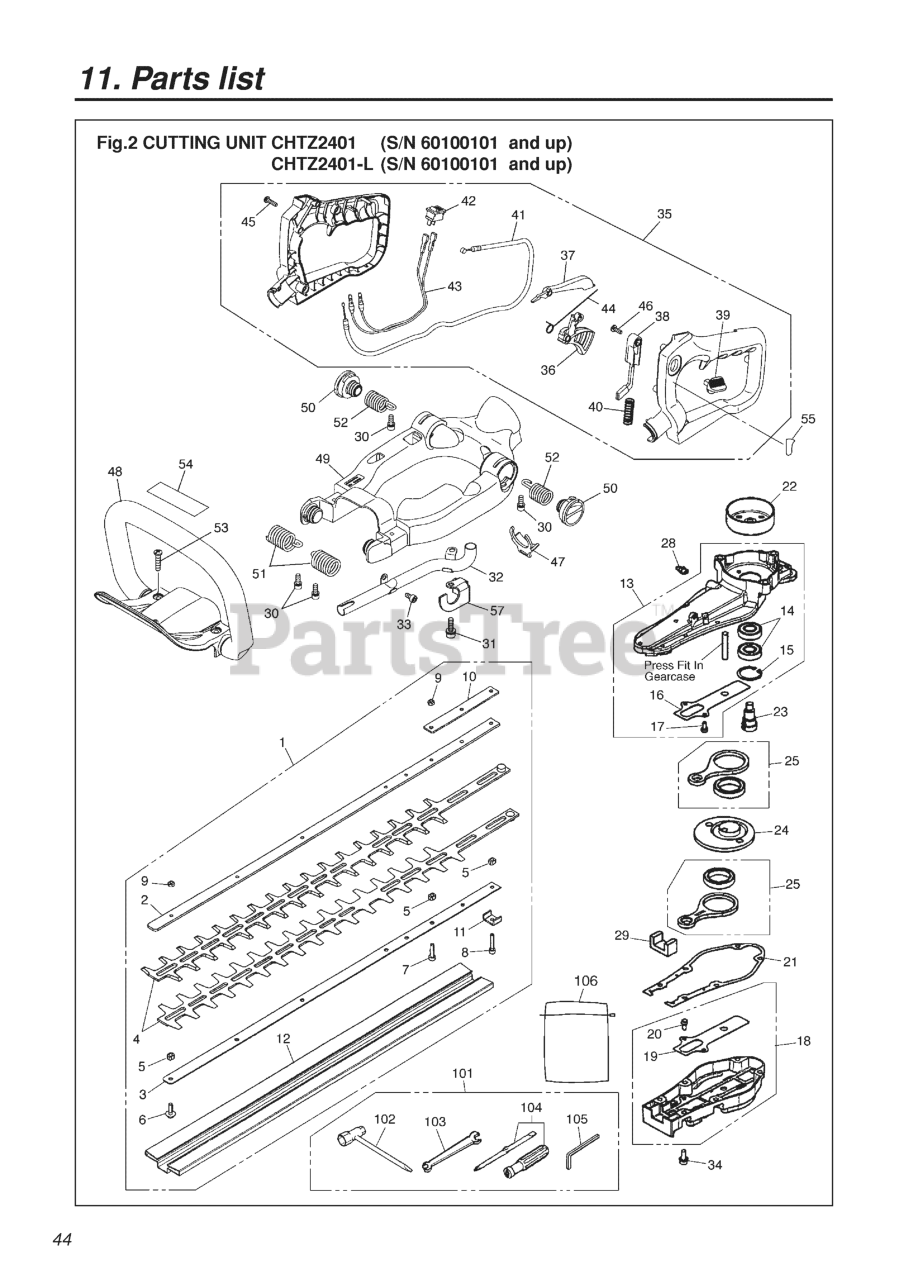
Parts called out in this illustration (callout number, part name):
1	BLADE ASSY
2	PLATE,UPPER
3	PLATE,LOWER
4	BLADE
5	SPACER
6	SCREW, BLADE
7	BOLT, M5 X 20
8	BOLT
9	NUT
10	PLATE
11	BRACKET (RPLS T4543-11510)
12	COVER, BLADE
13	GEARCASE-C (RPLS. -6111)
14	BEARING
15	RING, SNAP, M28 x 1.2
17	BOLT
18	CASE-BOTTOM-A
20	BOLT
21	GASKET
23	GEAR, DRIVE
24	GEAR, DRIVEN
25	ROD-A
28	FITTING, GREASE
29	FELT
30	BOLT (REPLACES 01252-30514)
31	BOLT, M6 X 25
32	PIPE-EXHAUST
33	BOLT, M5 X 10
34	BOLT
35	HANDLE-REAR-A
36	LEVER-THROTTLE
38	LEVER-LOCK
39	KNOB
40	SPRING
41	CABLE C
42	SWITCH
43	CORD COMP.
44	SPRING
45	SCREW
46	SCREW (REPLACES 50030272)
47	STOPPER
48	HANDLE F
49	FRAME
50	HOLDER-REAR
52	SPRING
54	LABEL, CAUTION
57	BRACKET
101	TOOL-SET
103	SPANNER, 8 X 10 (RPLS 2540- )
104	SCREWDRIVER
105	WRENCH (TOOL)
